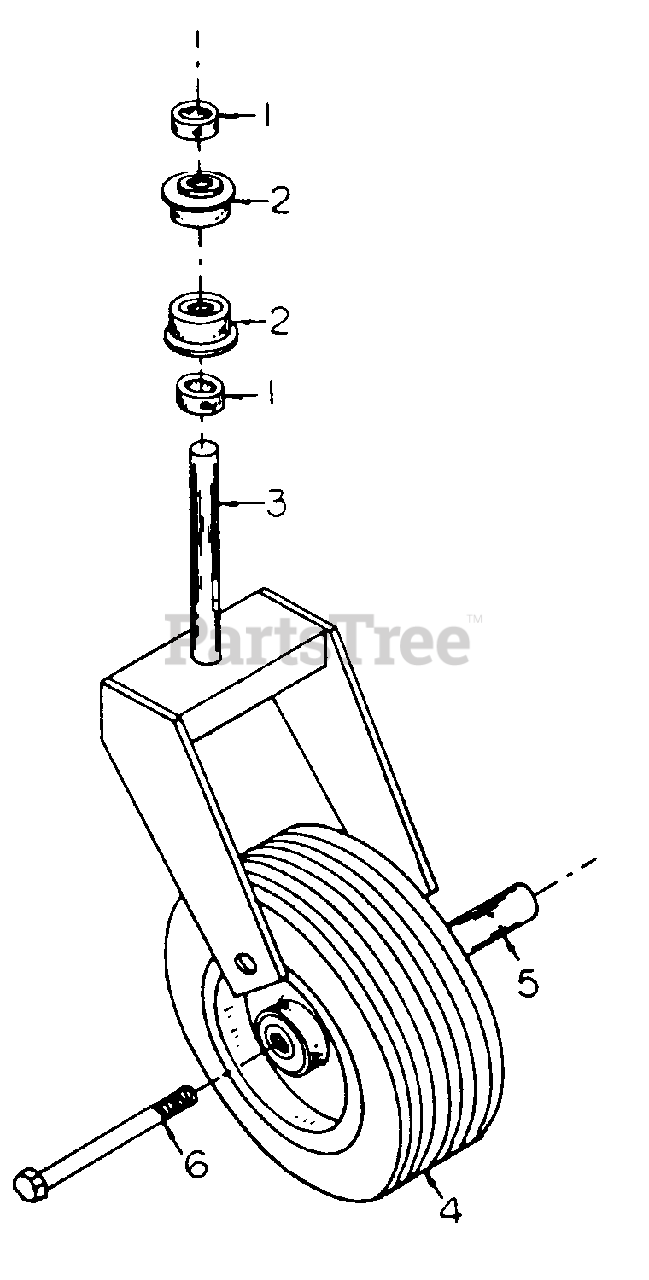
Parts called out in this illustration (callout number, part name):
1	Set Collar, 1 1/4"
2	Bearing, 1 1/4"
3	Tall Wheel Fork
4	Wheel Assembly
6	Bolt, 1/2-13 x 9 1/2"
